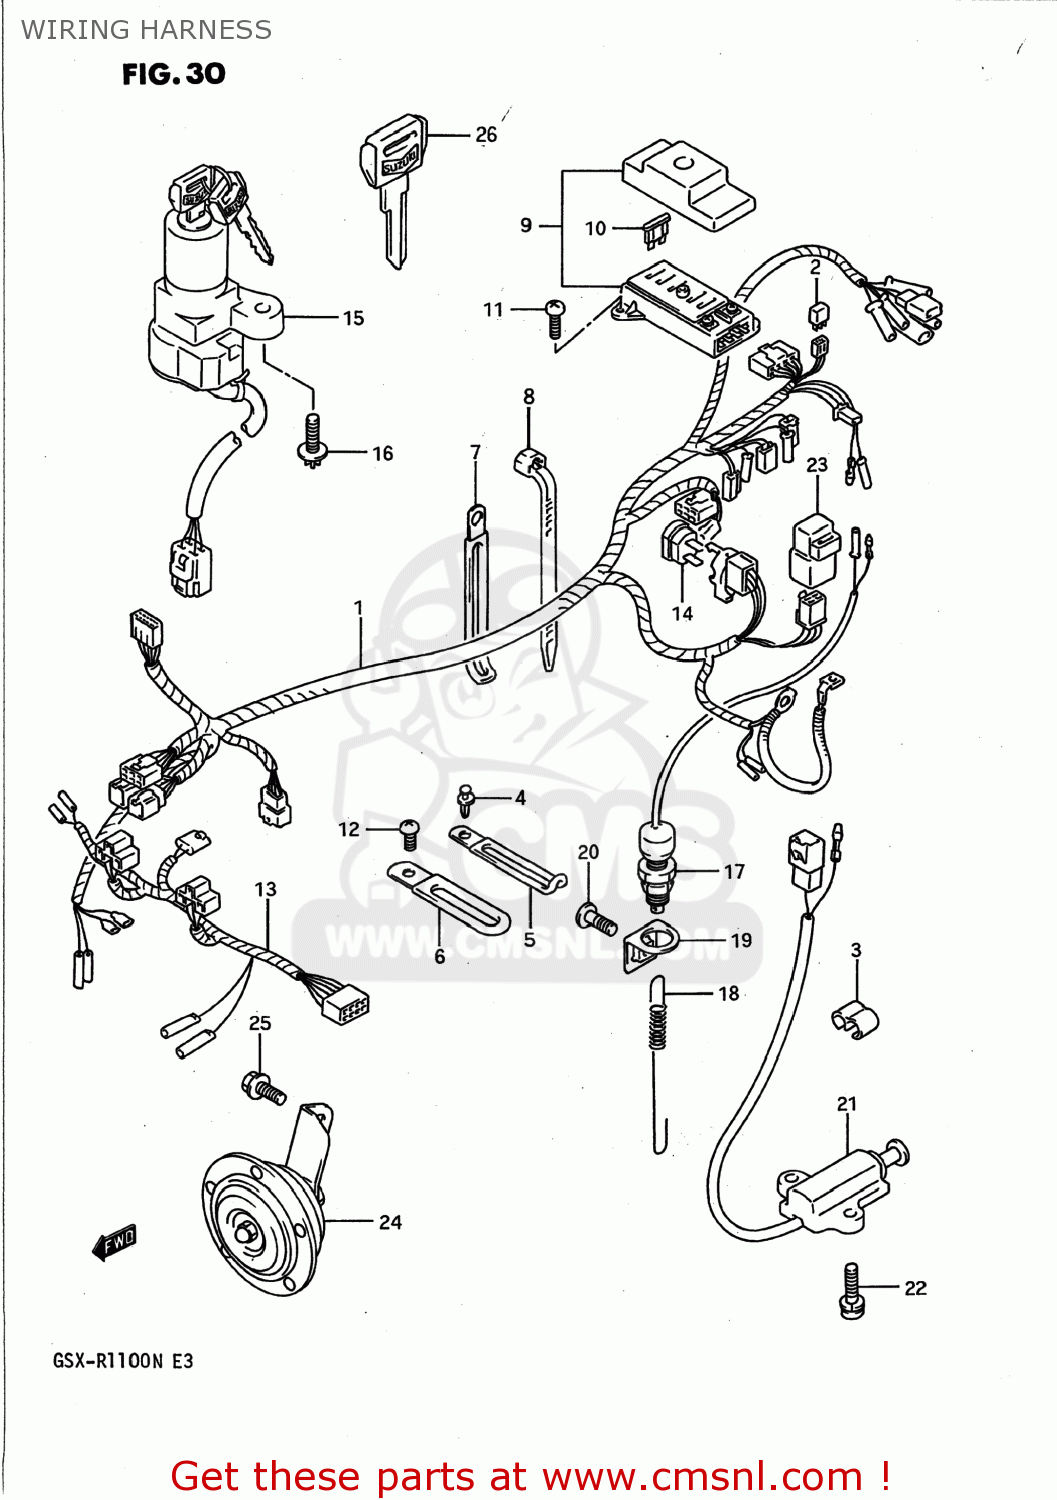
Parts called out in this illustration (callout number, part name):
1	HARNESS,WIRING
2	DIODE(STANLEY DE8804)
3	CLIP
4	CLIP
5	CLAMP
6	CLAMP
7	CLAMP
8	CLAMP(L:95)
9	BOX ASSY,FUSE
10	FUSE(10A)
11	SCREW
12	SCREW
13	WIRE,HEADLAMP LEAD
14	BREAKER ASSY,CIRCUT
15	LOCK ASSEMBLY,STEERING
16	SCREW(6X18)
17	SWITCH ASSY,STOP LAMP
18	SPRING
19	BRACKET,STOP LAMP SWITCH
20	SCREW(6X12)
21	SWITCH ASSEMBLY,SIDE STAND
22	SCREW
23	RELAY ASSEMBLY
24	HORN ASSEMBLY
25	BOLT
26	KEY,BLANK
